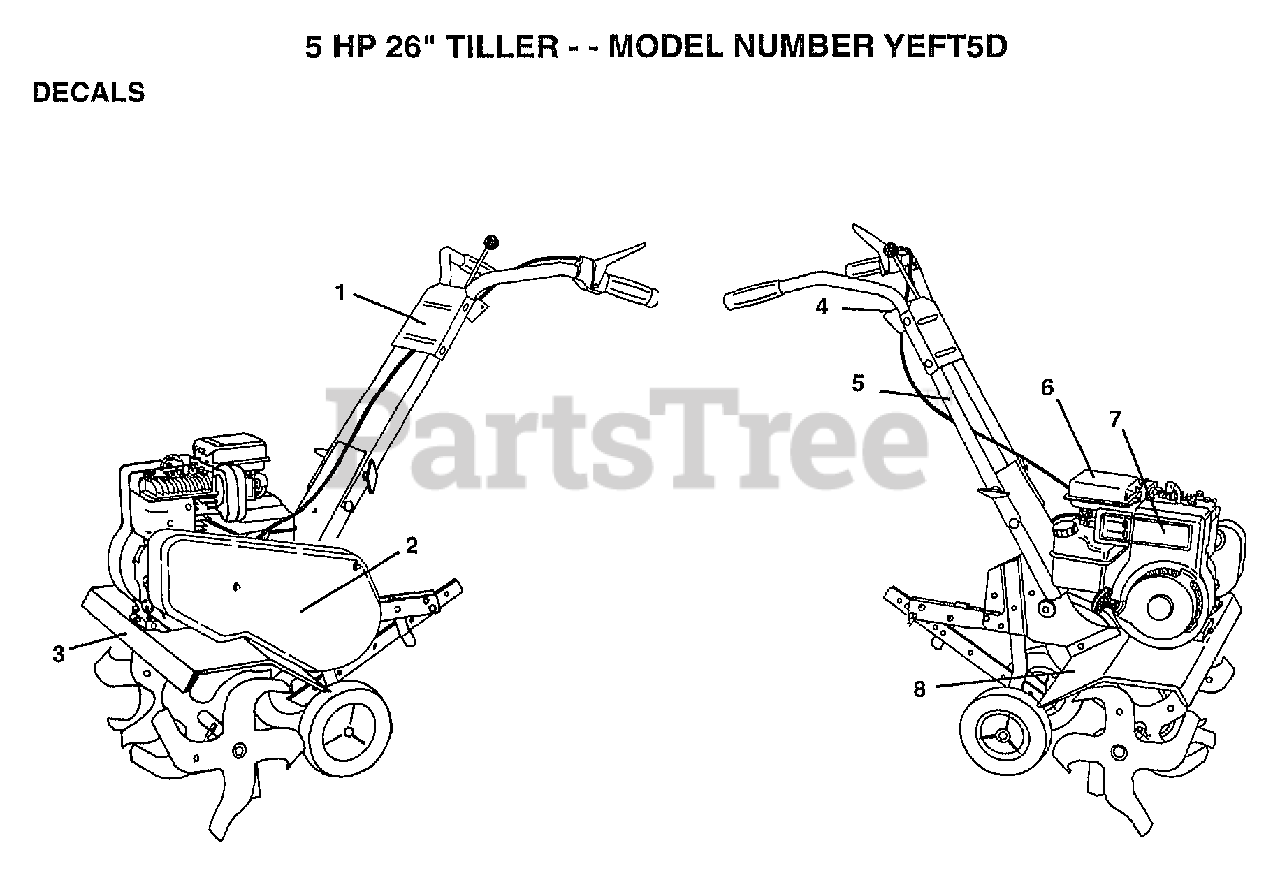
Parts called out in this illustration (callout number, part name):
1	"DECAL,HD BR TI "
2	DECAL.BELT.GD.5HP
3	DECAL.SHIELD.TINE
4	DECAL REVERSE
5	DECAL TI
6	DECAL TI
